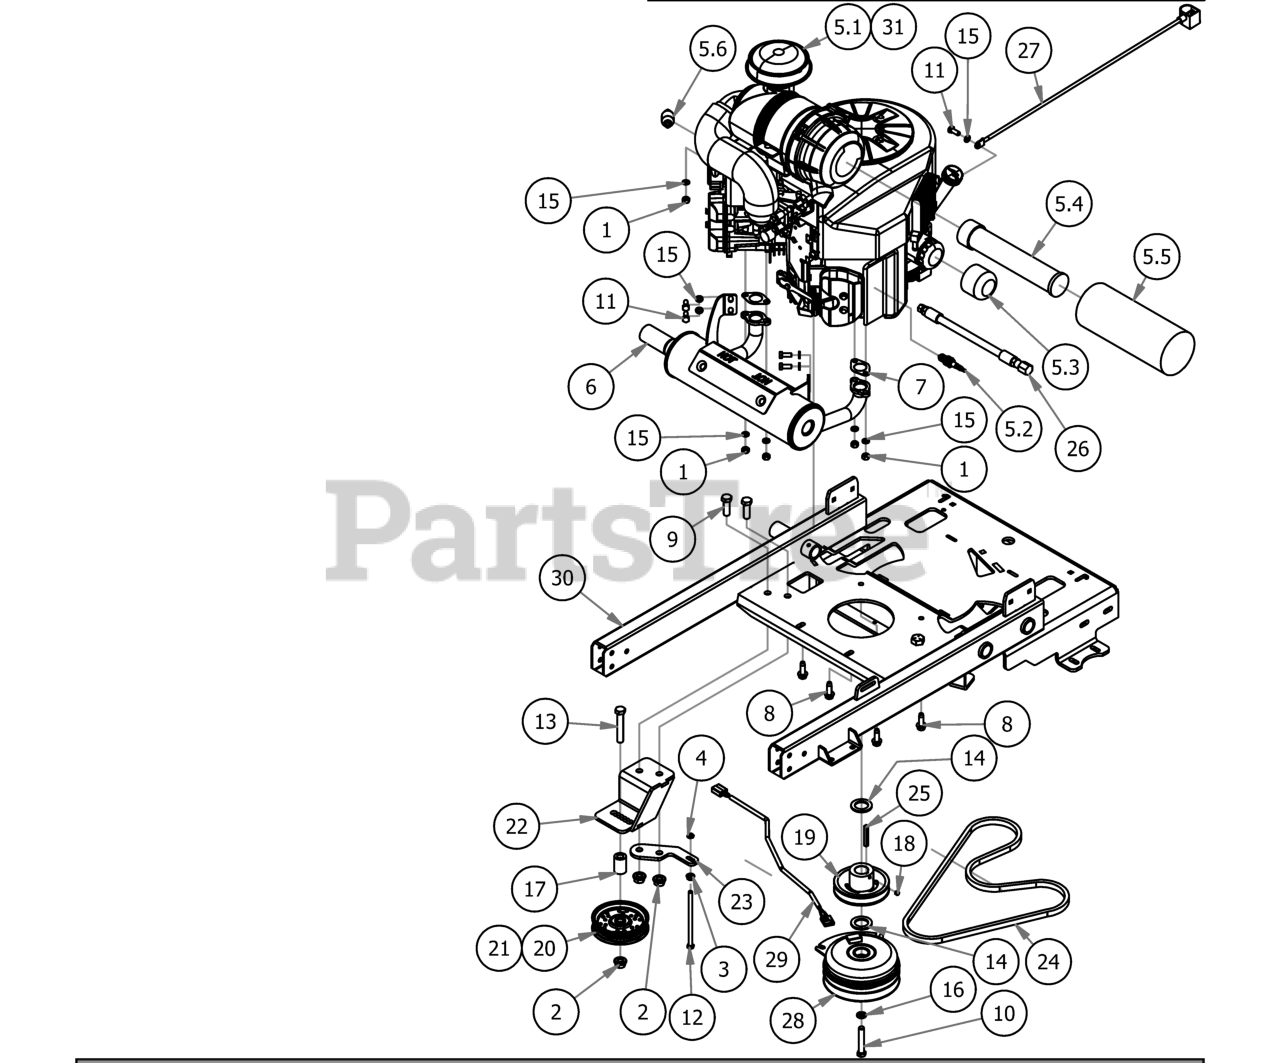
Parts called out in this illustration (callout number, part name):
1	M8-1.25 DIN 934 HEX NUT (CL.8) ZINC
2	1/2-13 NYLON INSERT FLANGE LOCKNUT ZINC
3	5/16-18 HEX SERRATED FLANGE NUT HARD/ZINC
4	5/16-18 NYLON INSERT JAM LOCKNUT ZINC
5	Kawasaki FX850 Engine
5.1	Kawasaki Engine FX-850-V-CS09R
5.2	Spark Plug - Kawasaki
5.3	Oil Filter
5.4	Canister Air Filter- Inner
5.5	Canister Air Filter- Outer
5.6	Universal Inline Fuel Filter
6	Revolt Kawasaki FX850 Exhaust
7	Exhaust Gasket
8	3/8-16 X 1-1/8HEX WASHER UNSLOT SERRATED (TRI-LOB) TRS
9	1/2-13 X 1-1/2 HEX CAP SCREW (GR.5) ZINC
10	7/16-20 X 2-1/2 HEX CAP SCREW (GR.8) ZINC YELLOW
11	M8-1.25 X 20MM DIN 933 HEX TAP BOLT (CL 8.8) ZINC
12	5/16-18 X 5-1/2 HEX CAP SCREW (GR.5) ZINC
13	1/2-13 X 3 HEX CAP SCREW (GR.5) ZINC
14	1.140 ID X 1.750 OD X .132 THICK FLAT WASHER PLAIN
15	5/16 SPLIT LOCKWASHER ZINC
16	7/16 SPLIT LOCKWASHER (GR.8) ZINC YELLOW
17	.502 ID X .750 OD X 1.500 Long Spacer
18	5/16-24 X 1/4 SOCKET SET SCREW (CUP PT) PLAIN
19	4 3/4 Motor Pulley
20	4 3/4 Idler Pulley - ABFI-76 (54" Deck Only)
21	5 3/4 Idler Pulley-Don Dye (61" Deck Only)
22	Idler Pulley Bracket Weldment
23	2019 Stand On Clutch Stop Bracket
24	2019 Stand On Pump Belt (Timken# 47-2827)
25	1/4 X 2 SQ MACHINERY KEY 1018 STL PLAIN
26	Kawasaki Oil Drain
27	24" Black Ground Cable
28	Clutch Assembly
29	Clutch Pigtail
30	2019 Stand On Frame Weldment
31	Kawasaki Harness Adapter
